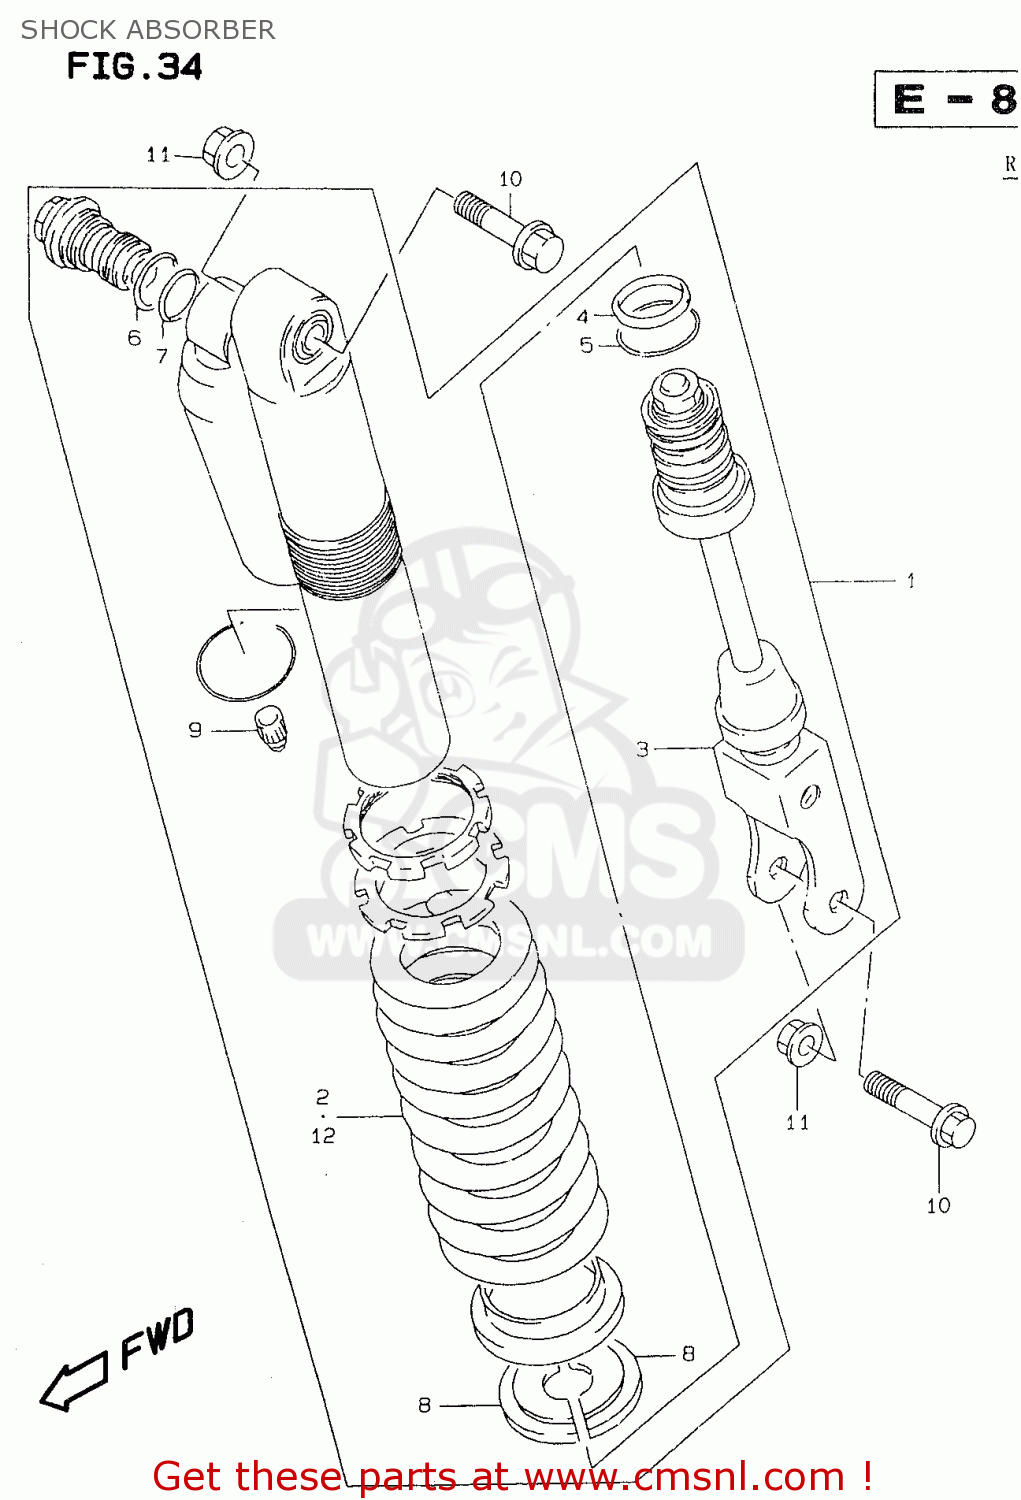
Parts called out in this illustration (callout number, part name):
1	ABSORBER ASSY,REAR SHOCK (PURPLE)
2	SPRING
3	ROD,PISTON
4	O RING
5	RING,PISTON ROD STOPPER
6	O RING
7	O-RING,FORK BOLT,LOWER
8	SEAT,SPRING STOPPER
9	CAP
10	BOLT,RR CUSHION ROD UPR
11	NUT
12	SPRING(SOFT)
